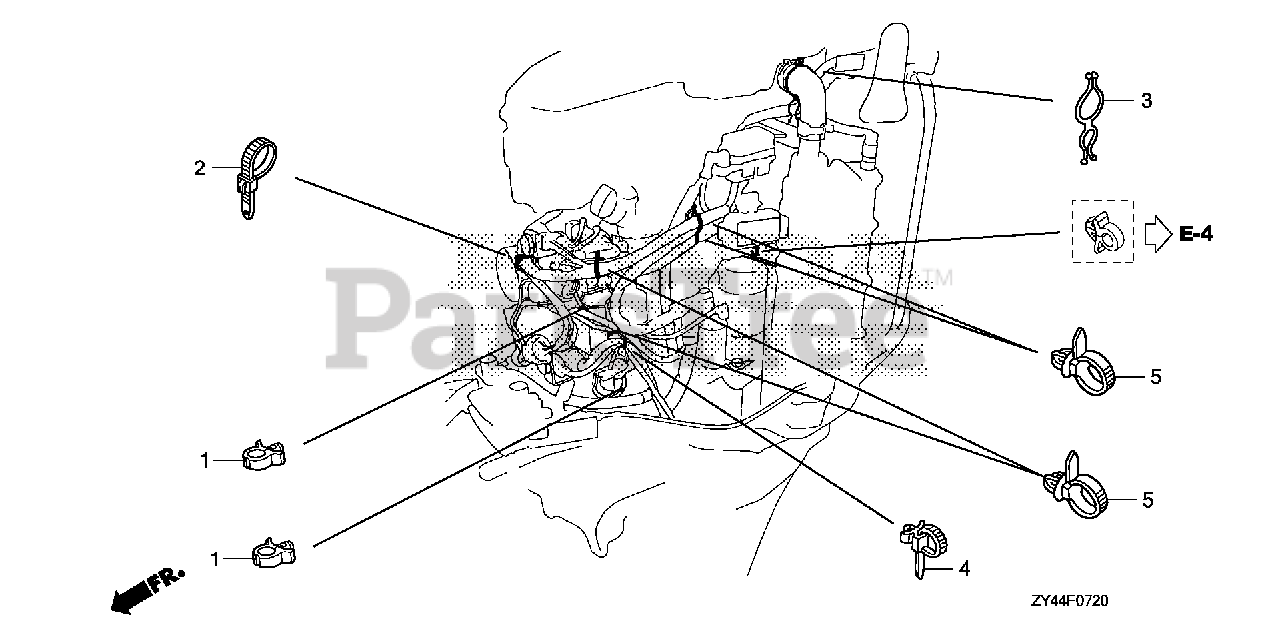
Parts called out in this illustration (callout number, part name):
1	CLIP, BRAKE PIPE (A)
2	TIE, CABLE
3	CLIP B, HARNESS
4	STRAP, CABLE (118MM) (BLACK)
5	CLIP, HARNESS BAND (145MM) (BLACK)
